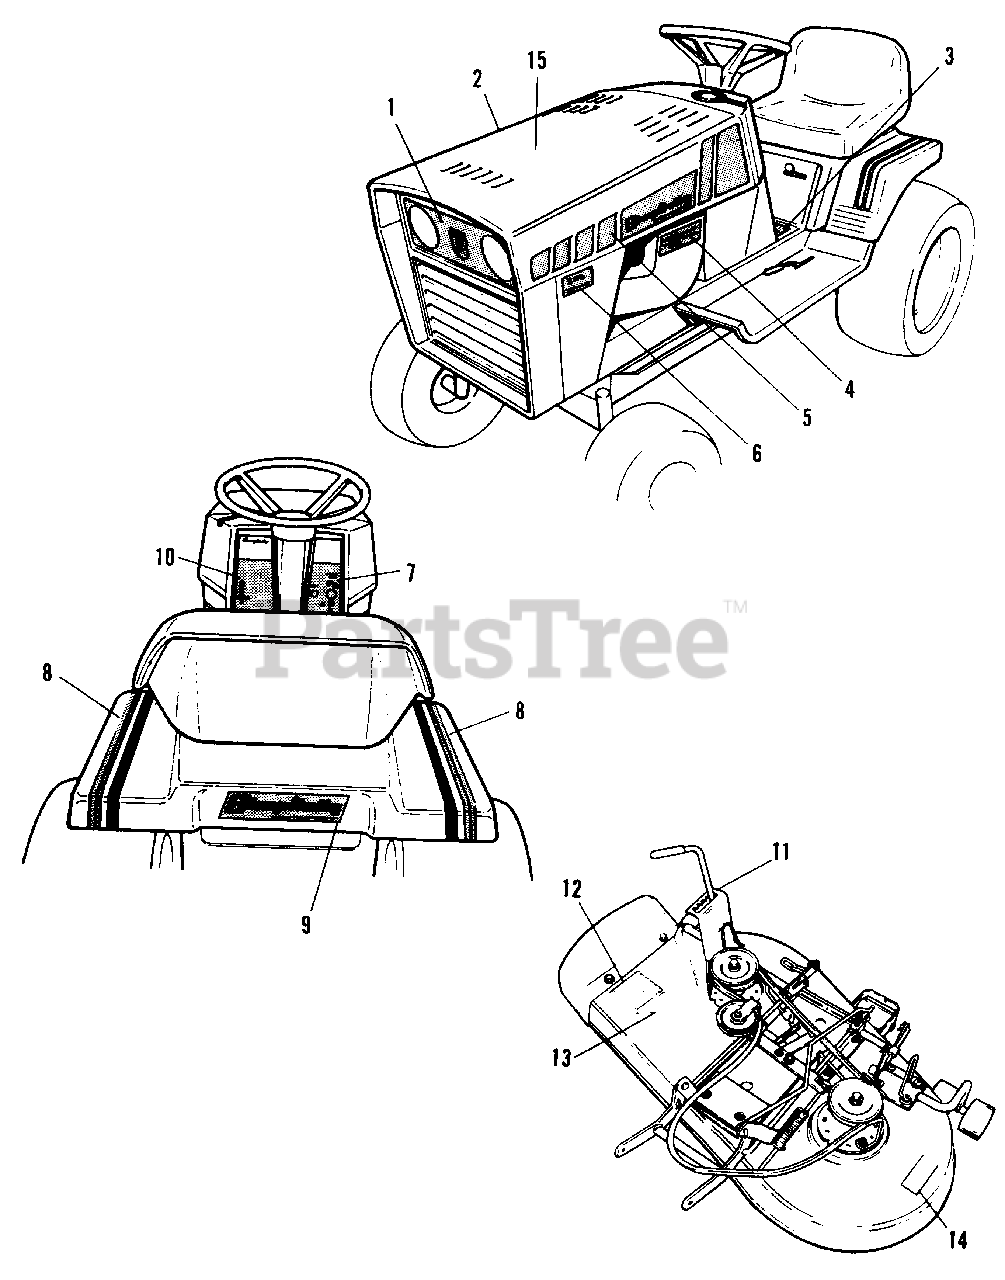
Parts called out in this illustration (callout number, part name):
1	DECAL, Grille (1690629 only)
1	DECAL, Grille (1690684, 1690849, 1690879, 1690915 8 1690934 only)
2	DECAL, Hood, R.H.
3	DECAL, Shift (1690629 only)
3	DECAL, Shift (1690684, 1690849, 1690879, 1690915 & 1690934 only)
4	DECAL, Engine (1690629 only)
4	DECAL, Engine (1690684, 1690849, 1690879 only)
4	DECAL, Engine (1690915 & 1690934 only)
5	DECAL, Hood, L.H.
6	DECAL, 5116 Special (1690629, 1690684, only)
6	DECAL, 5216 Special (1690849, 1690879, 1690915 & 1690934 only)
7	DECAL, Dash, R.H. (1690629 only)
7	DECAL, Dash, R.H. (1690684, 1690849, 1690879)
8	DECAL, Seat Deck
9	DECAL, Simplicity
10	DECAL, Dash, L.H.
11	DECAL, Mower Height
12	DECAL, Warning
13	DECAL, OPEI
14	DECAL, Danger
15	DECAL, Drive Belts (Inside Hood) (1690629, 1690684, only)
15	DECAL, Drive Belts (Inside Hood) (1690849, 1690879, 1690915 & 1690934 only)
